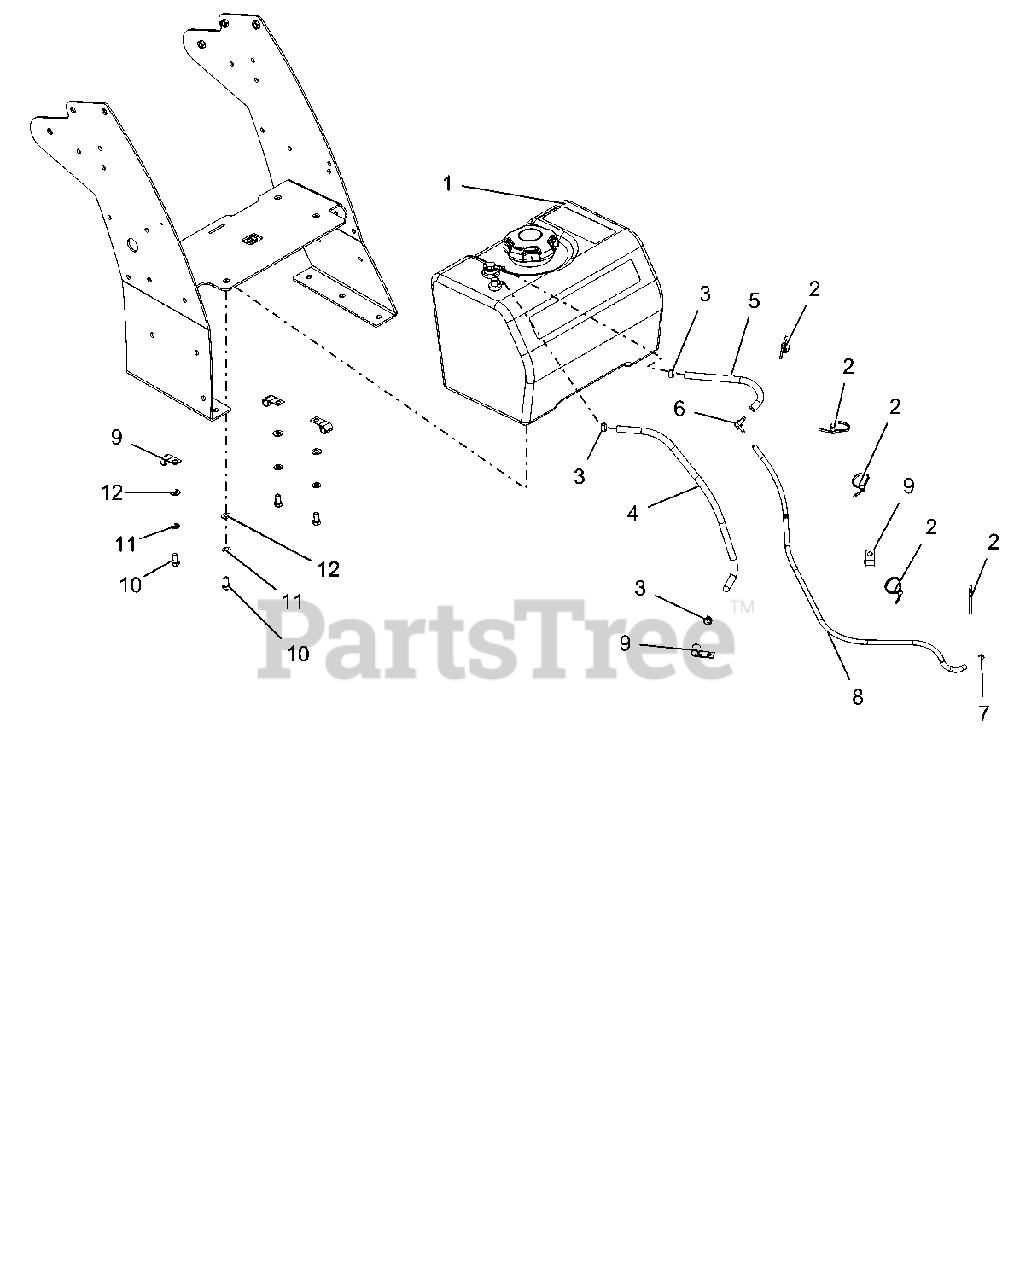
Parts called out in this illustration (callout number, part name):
1	TANK, FUEL LOW PERM
2	CABLE TIE, .15 X 8.50
3	CLAMP, FUEL LINE
4	HOSE, FUEL 1/4 X 18.00
5	HOSE, FUEL HYDRO TANK - ROV
6	FITTING-3/16X1/4 90DEGREE VAC
7	CLAMP - HOSE, SPRING .188
8	SAE LOW CARB 3/16" X 37"
9	P-CLIP, .500 INSULATED
10	BLT-HEX .38-16X.75 GR5 YWZC
11	WSHR-LK .38X.094 REG YWZC
12	WSHR-FL-STL.406X.812X.065 YWZ
